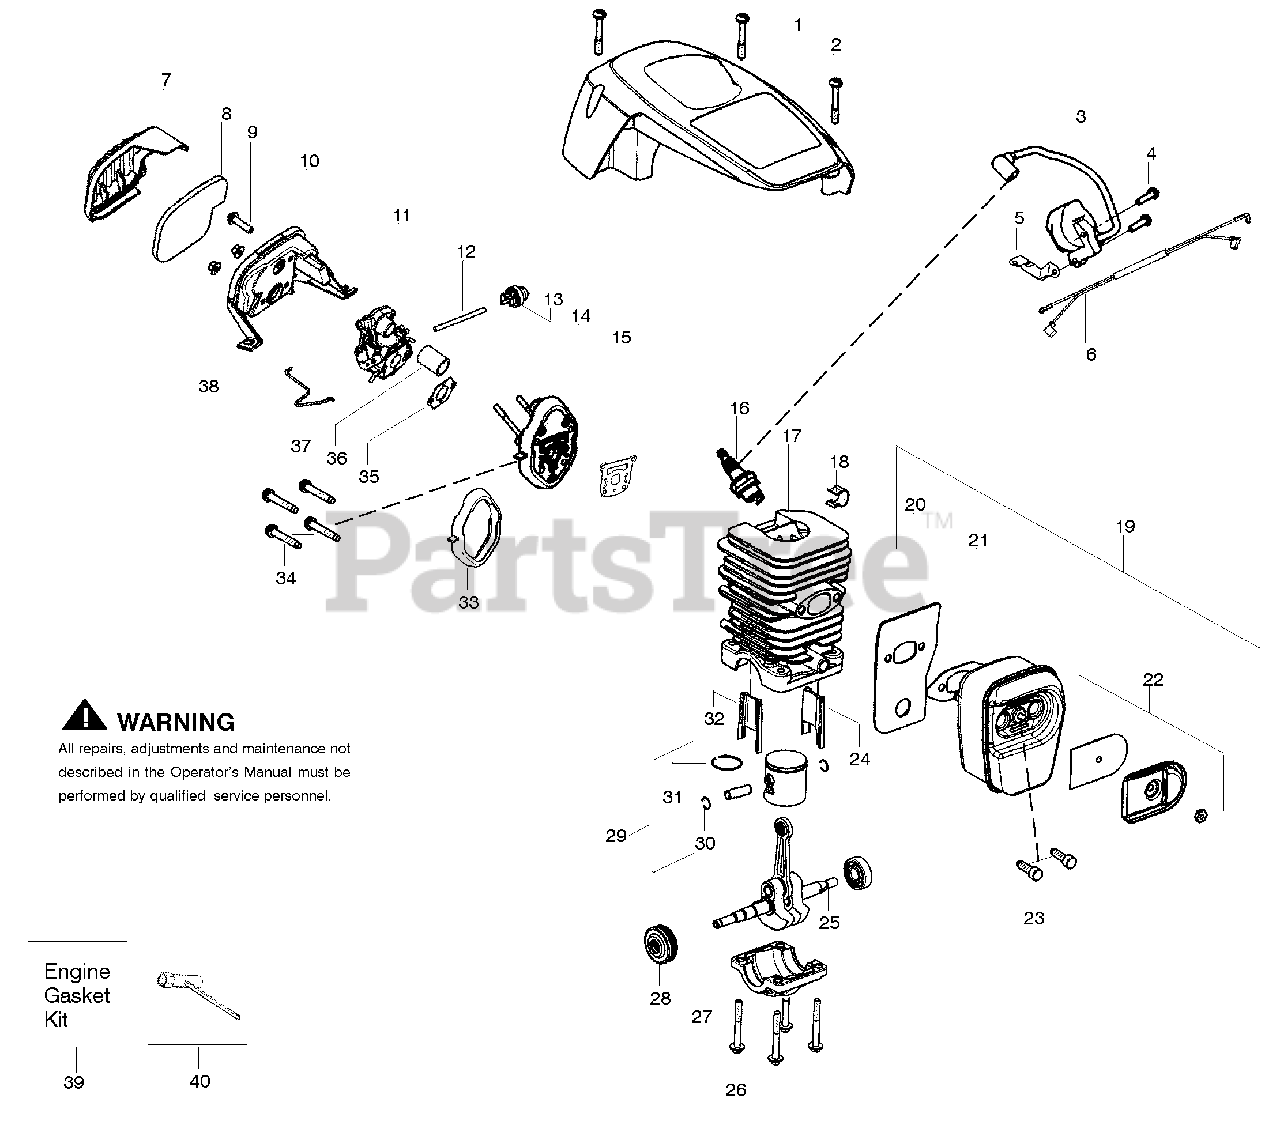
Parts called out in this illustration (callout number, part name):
1	Shield-Cylinder
3	Module - Ignition
5	Strap-Ground
6	Assy-Wire Harness
7	Cover-Air Filter
8	Filter-Air
10	Housing-Air Filter
11	Carburetor Zama W-26
12	Kit-Fuel Line (Small)
13	Bulb-Purge "snap-in"
14	Kit-Carb. Adaptor
15	Gasket-cyl. (kit)
16	Accy-Spark Plug (RCJ-7Y)
17	Kit-Cylinder
18	Clip-High Tension Lead
19	Kit-Muffler
20	Backplate-Muffler
21	Gasket-Muffler (kit)
22	Kit-Spark Arrestor
23	Bolt-Muffler
24	Insert-Left (black) Cyl.
25	Assy-Crankshaft/Rod
27	Cap-Crankcase
28	Assy-Bearing/Seal
29	Kit-Piston
30	Retainer-Piston Pin
31	Ring-Piston
32	Insert-Right (gray) Cyl.
33	Seal-Adaptor (kit)
35	Gasket-Carb. (kit)
36	Tube-Intake
37	Wire-Throttle
38	Nut-Carb.
39	Kit-Gasket
40	Bar wrench
